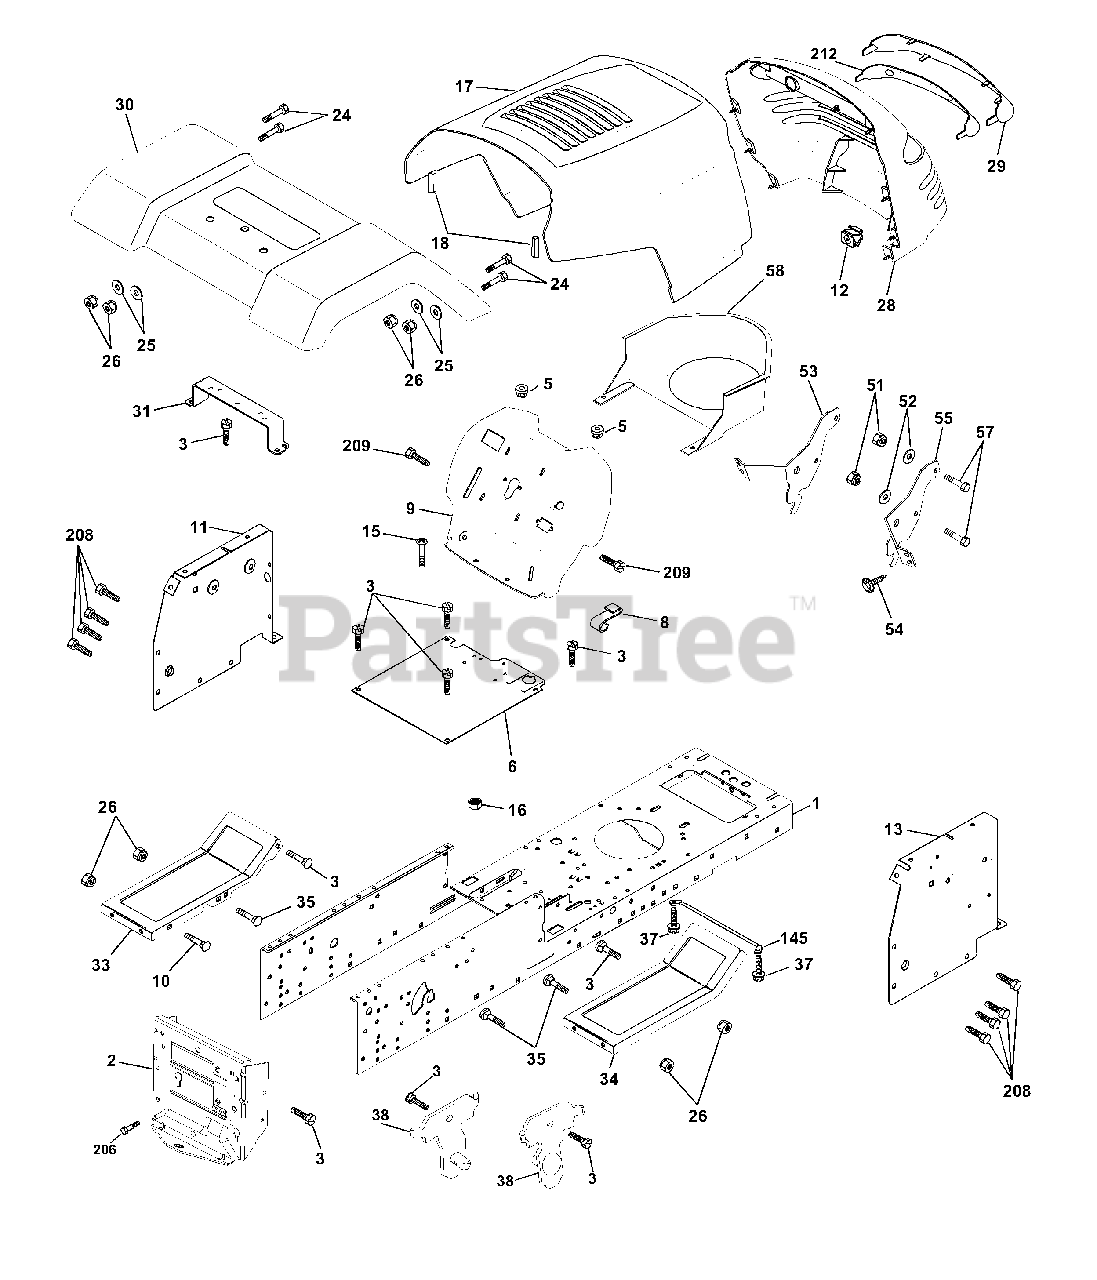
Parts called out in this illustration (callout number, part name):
2	Drawbar
3	Screw 3/8-16 x 3/4
5	Bumper Hood/Dash
6	Saddle Flat Lt
8	Clip Retainer Slide-On
9	Dash
10	Bolt Rd Hd Sqnk. 3/8-16 Unc x 1
11	Panel Asm. Dash Lh
12	Clip Tinnerman Grile P/L
15	Screw Mach Trhd 5/16-18 Unc x 3/4
16	Nut Keps 5/16-18 Unc
17	Hood
18	Bumper Hood
24	Bolt Fin Hex 3/8-16 Unc x 1 Gr. 5
25	Washer 13/32 x 13/16 x 12 Ga.
26	Nut Lock Hex w/Insert 3/8-16 UNC
28	Grill/Lens Asm
29	Lens Grille Private label
31	Bracket Fender
33	Footrest
34	Footrest
35	Bolt Rd Hd Sht. Sqnk. 3/8-16 x 3/4
37	Screw Thdrol 5/16-18 x 1/2 Tyt
38	Bracket Asm. Pivot Mower Rear
51	Nut Lock Hex W/Ins. 1/4-20
52	Washer 9/32 x 7/8 x 16 Ga.
53	Bracket Grille LH
54	Screw Hex Wshd 8-18 x 7/8
55	Bracket, Grille RH
57	Bolt Fin Hex 1/4-20 x .75
58	Air Duct Private Label
145	Rod Pivot Chassis/Hood
206	Bolt shoulder 5/16-18
208	Screw Thdrol 3/8-16 x 1/2
209	Screw Hex Wsh Thdrol 3/8-16
212	Insert Lens Reflector
